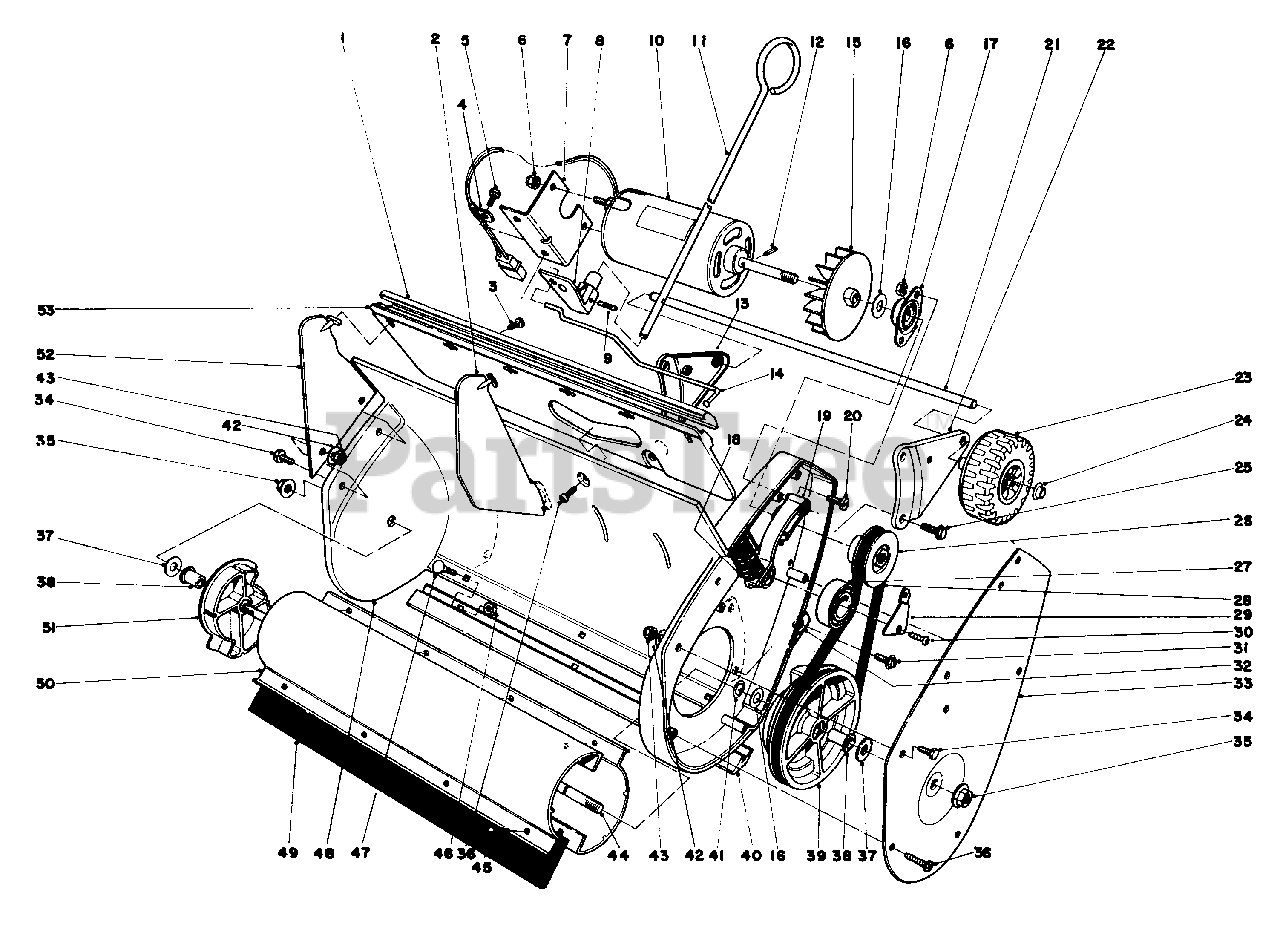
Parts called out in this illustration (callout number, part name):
1	Moulding
2	Vane-Inner
4	Insulated Closed Clip
7	Bracket-Mounting
8	Bracket-Vane Adjustment
9	Groove Pin
11	Rod-Vane Adjustment
12	Spring Pin
13	Bracket R.H.
14	Linkage Vane Adjustment
16	Thrust Washer
17	Side Flange Bearing
18	Idler Spring
19	Idler Arm
21	Axle Shaft
22	Wheel Bracket L.H.
24	Push Nut
25	Screw
26	Drive Pulley
27	Ball Bearing
28	Drive Belt
29	Retainer-Idler Pulley
32	Tinnerman Nut
33	Cover-Belt Case
36	Screw
37	Thrust Washer
38	Rotor Bushing
39	Pulley-Driven
41	Retaining Ring
42	Washer
44	Shaft-Rotor
45	Screw-Thread Forming
47	Carriage Bolt
48	Housing
49	Blade-Rotor
51	End Cap Rotor
52	Vane-Outer
53	Vane-Mount
